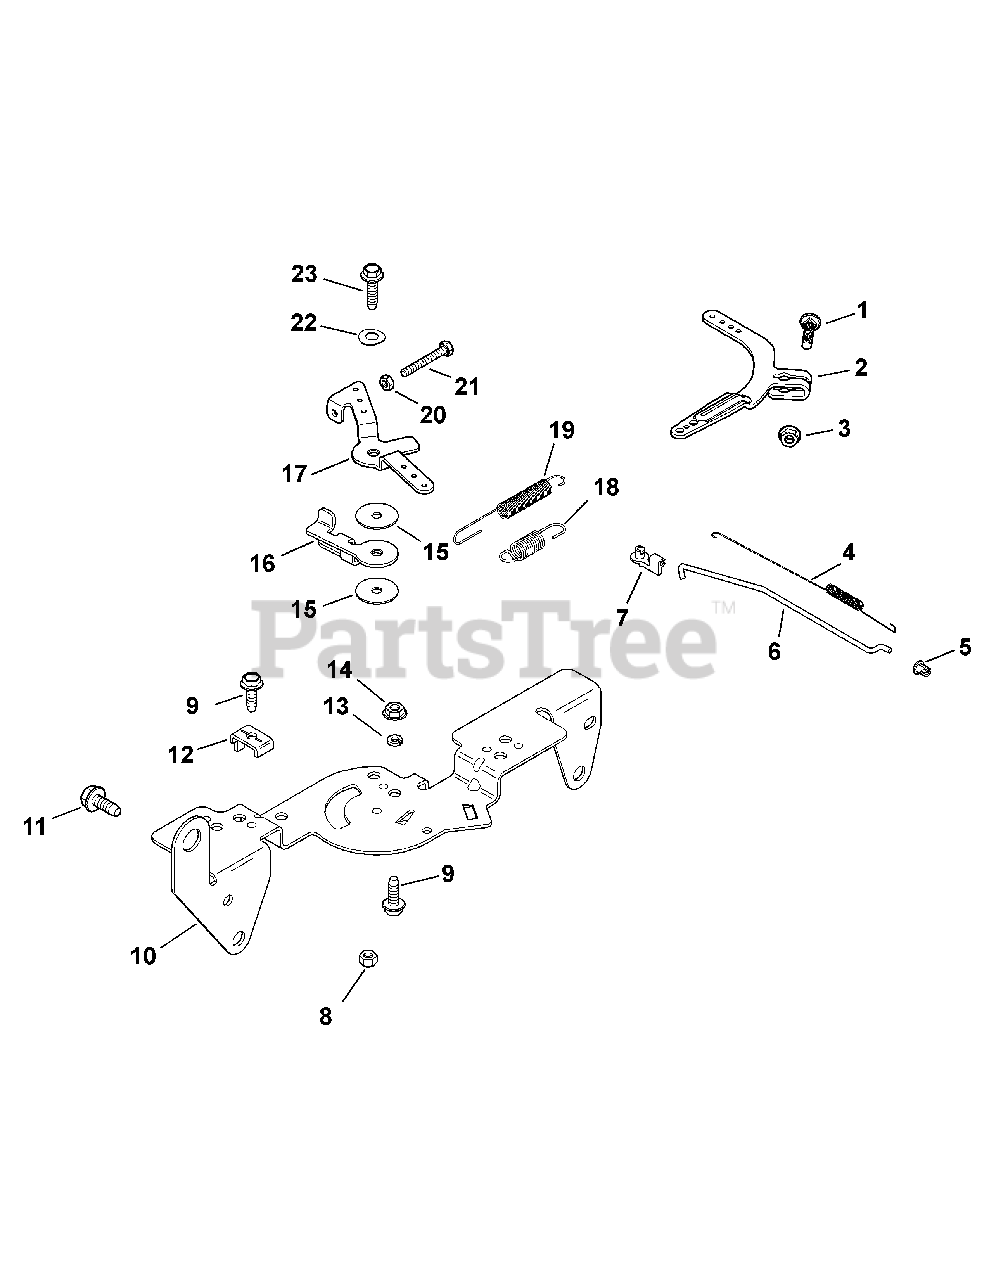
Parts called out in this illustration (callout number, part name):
1	BOLT, RD HD SQ NECK M6X1.0X25
2	LEVER, GOVERNOR
3	NUT, FLG M6X1.0
4	SPRING, LINKAGE
5	BUSHING, LINKAGE RETAINING
6	LINKAGE, THROTTLE
7	BUSHING, THROTTLE LINKAGE
8	NUT, LOCK M5X.8
9	SCREW, FLG THD FRM M5X0.8X16
10	BRACKET, CONTROL
11	SCREW, FLG THD FRM M6X1.0X16
12	CLAMP, CABLE
13	WASHER, SPRING LOCK 1/4"
14	NUT, FLG M5X.8
15	WASHER, FLAT 5.5 MM
16	LEVER, THROTTLE ACTUATOR
17	LEVER, THROTTLE CONTROL
18	SPRING, GOVERNOR
19	SPRING, THROTTLE LIMITER
21	SCREW, CAP M4X.7X30
22	WASHER, SPRING 1/4"
23	SCREW, FLG THD FRM M5X.8X20
